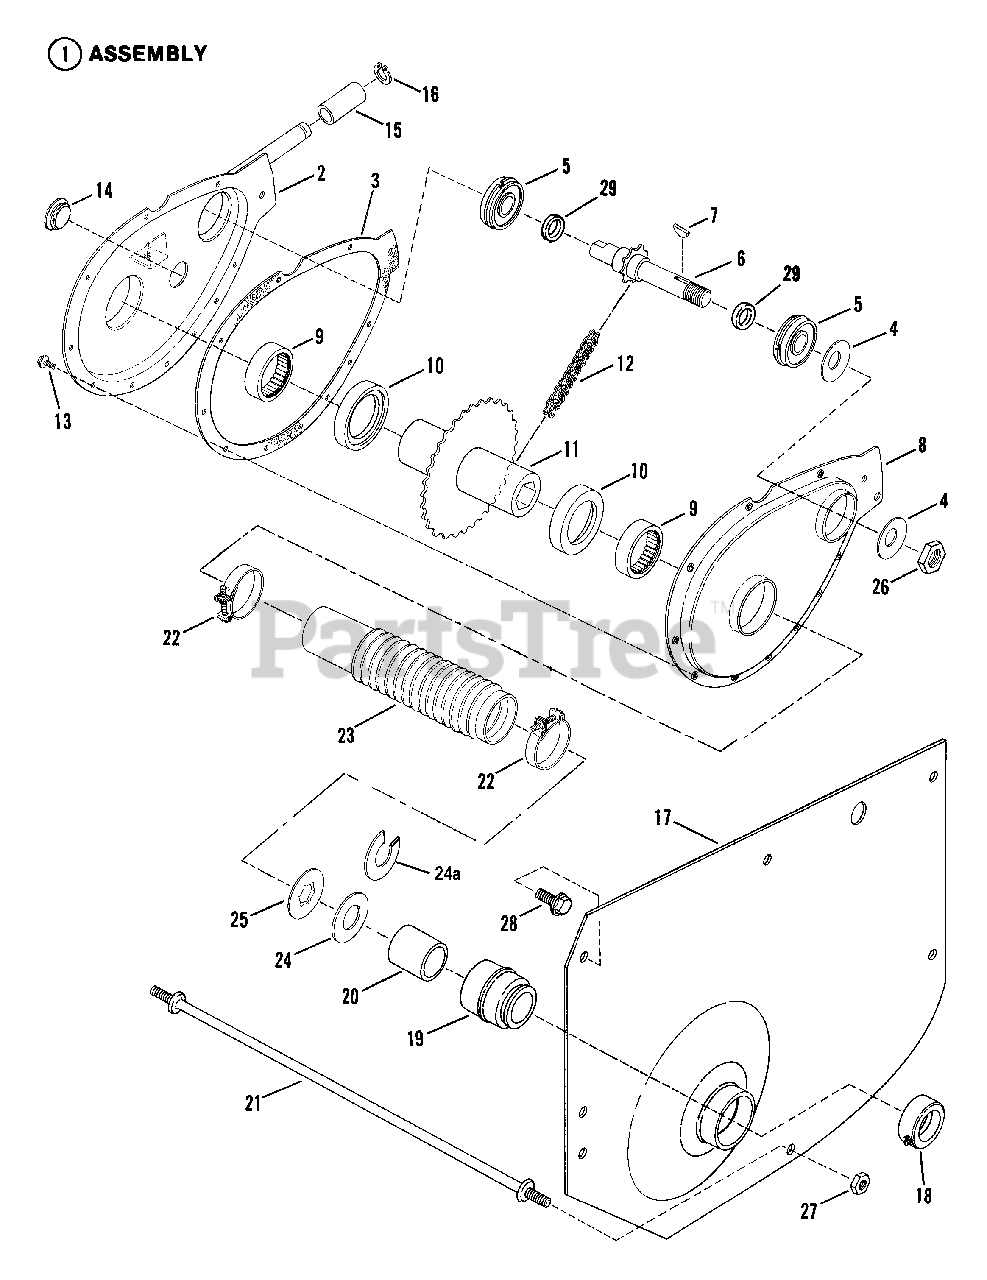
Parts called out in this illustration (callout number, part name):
1	ASSEMBLY, Chain Case
2	CASE, Sprocket
3	GASKET, Case Cover
4	WASHER, Belleville (2 in Assembly, 1 Loose)
5	BEARING, Ball
6	SPROCKET & SHAFT
7	KEY, Woodruff
8	COVER, Chain Case
9	BEARING, Needle
10	WASHER, Nylon Thrust
11	HUB & SPROCKET
12	CHAIN, 46 Pitch (#35)
13	SCREW, #10-24 x 1/2" Hex Washer Self-Tap (Torx)
14	PLUG, Oil Fill & Check
15	ROLLER
16	RING, Retaining
17	FENDER, Left Hand
18	COLLAR, Lock
19	BEARING, Left Hand Fender (.75" ID / 1.75" OD)
20	SPACER, Left Hand (.752" ID x .87" Long)
21	ROD, Cross-Tie
22	CLAMP, Boot
23	BOOT, Oil Seal
24	WASHER, Thrust Nylon
24A	WASHER, Shim
25	WASHER, Thrust Hex
26	NUT, 5/8-18 Hex Lock
27	NUT, 5/16-24 Hex
28	SCREW, 5/16-18 x 5/8" Self-Tapping
29	"O"-RING
30	KIT, Shim
